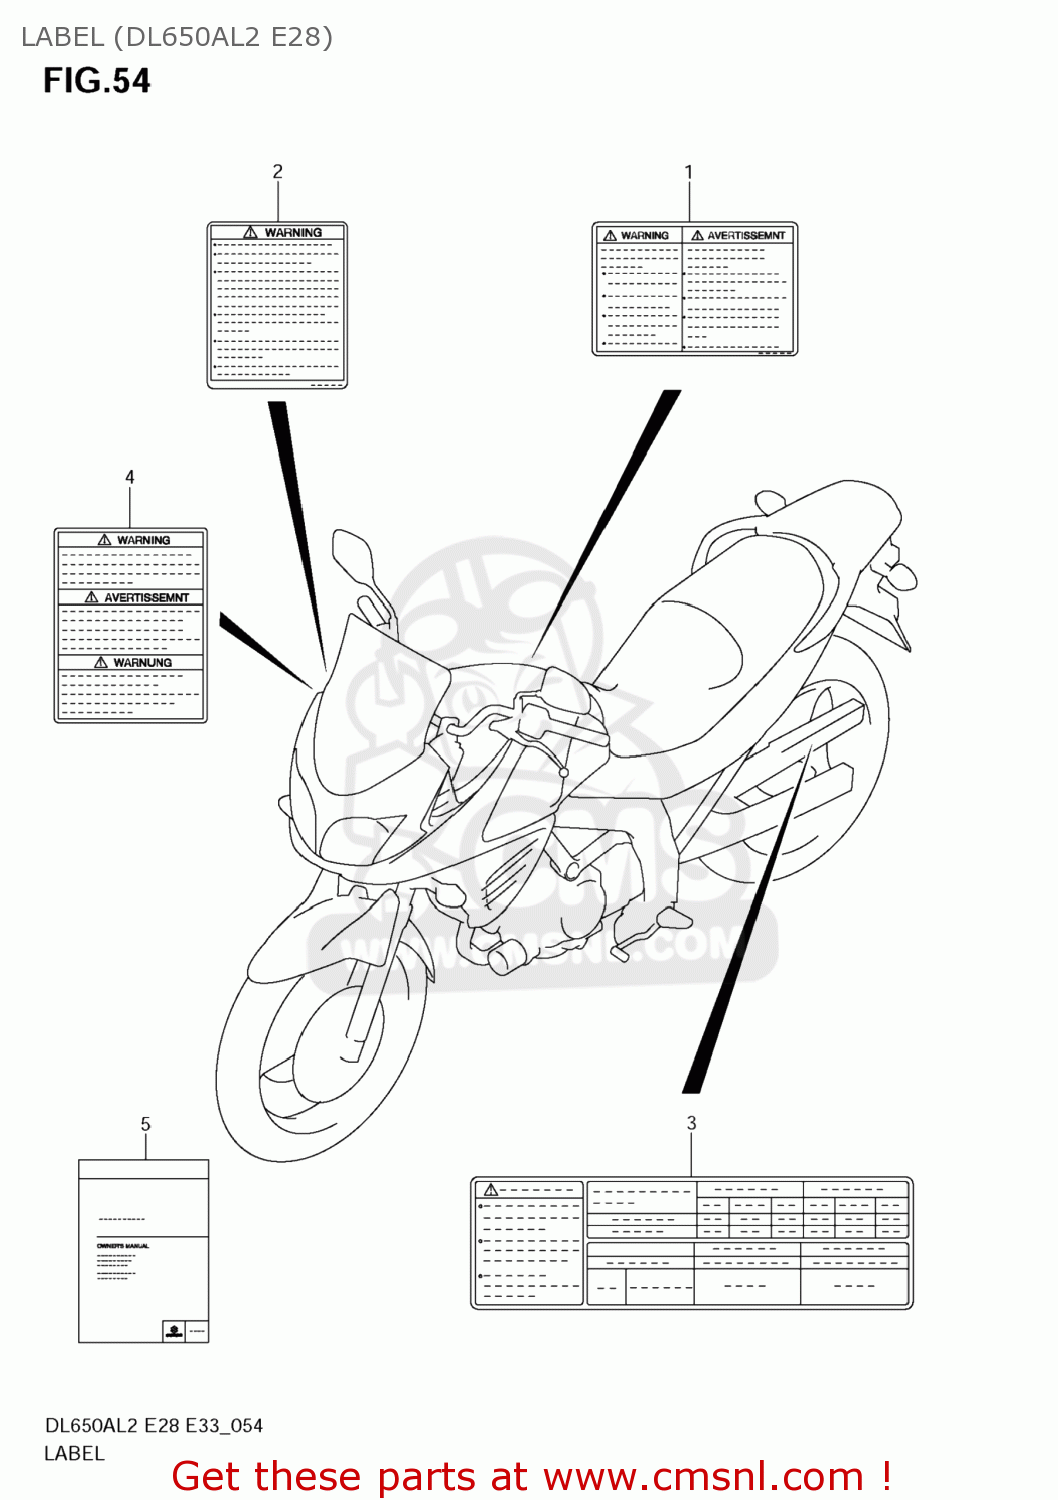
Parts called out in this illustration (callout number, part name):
1	LABEL,GENERAL WARNING
2	LABEL,SCREEN
3	LABEL,TIRE INFORMATION
4	LABEL,WARNING STEERING
5	MANUAL,OWNER'S
